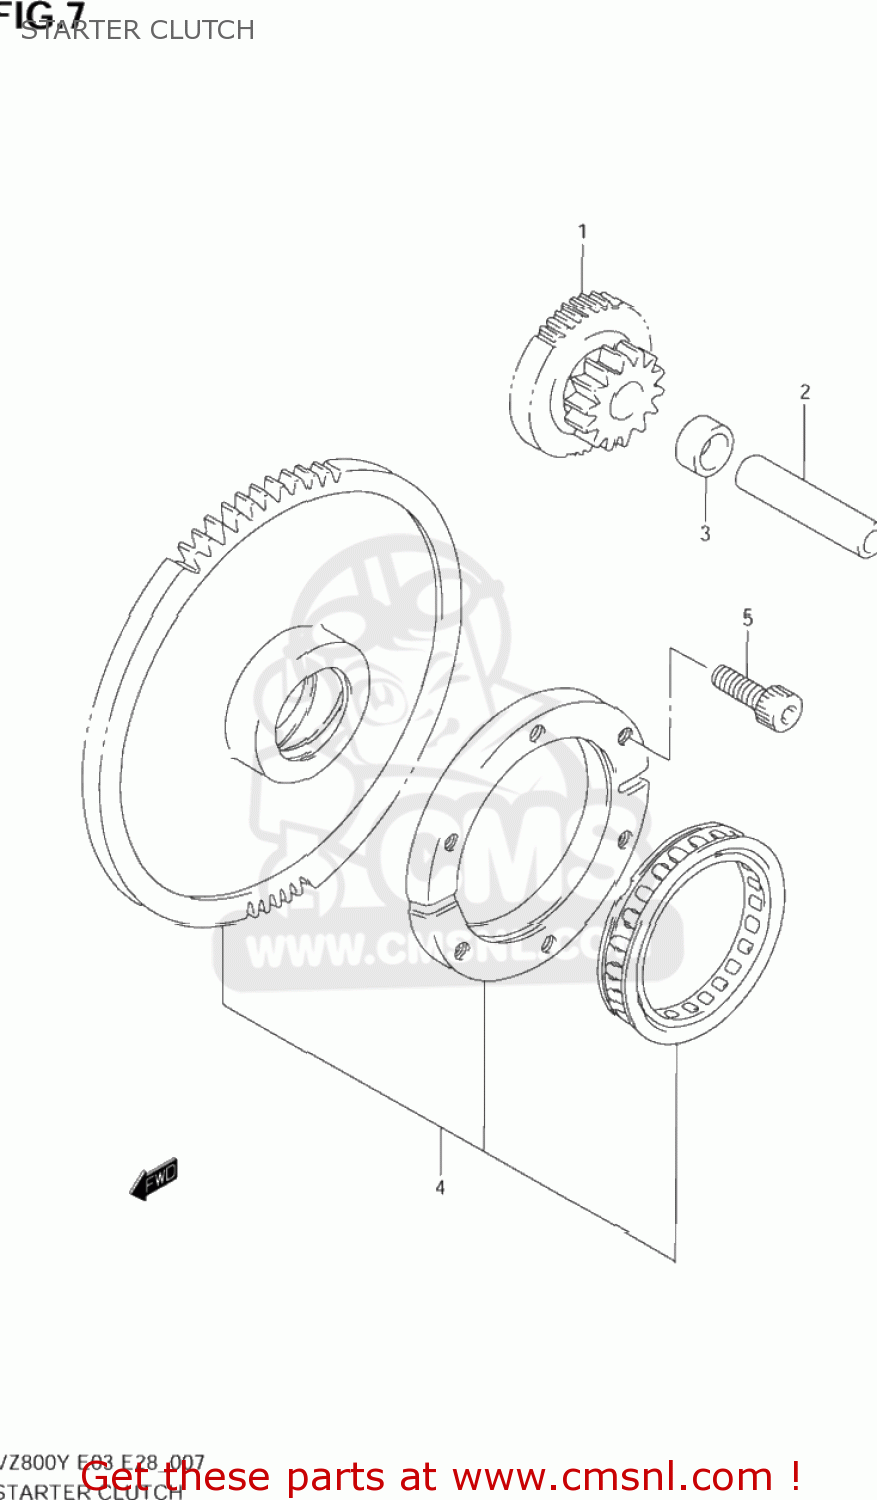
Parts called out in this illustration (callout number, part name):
1	GEAR,STARTER IDLE (NT
2	PIN(12X55.5)
3	SPACER(12.5X19X9.5)
4	CLUTCH SET,STARTER
5	BOLT
